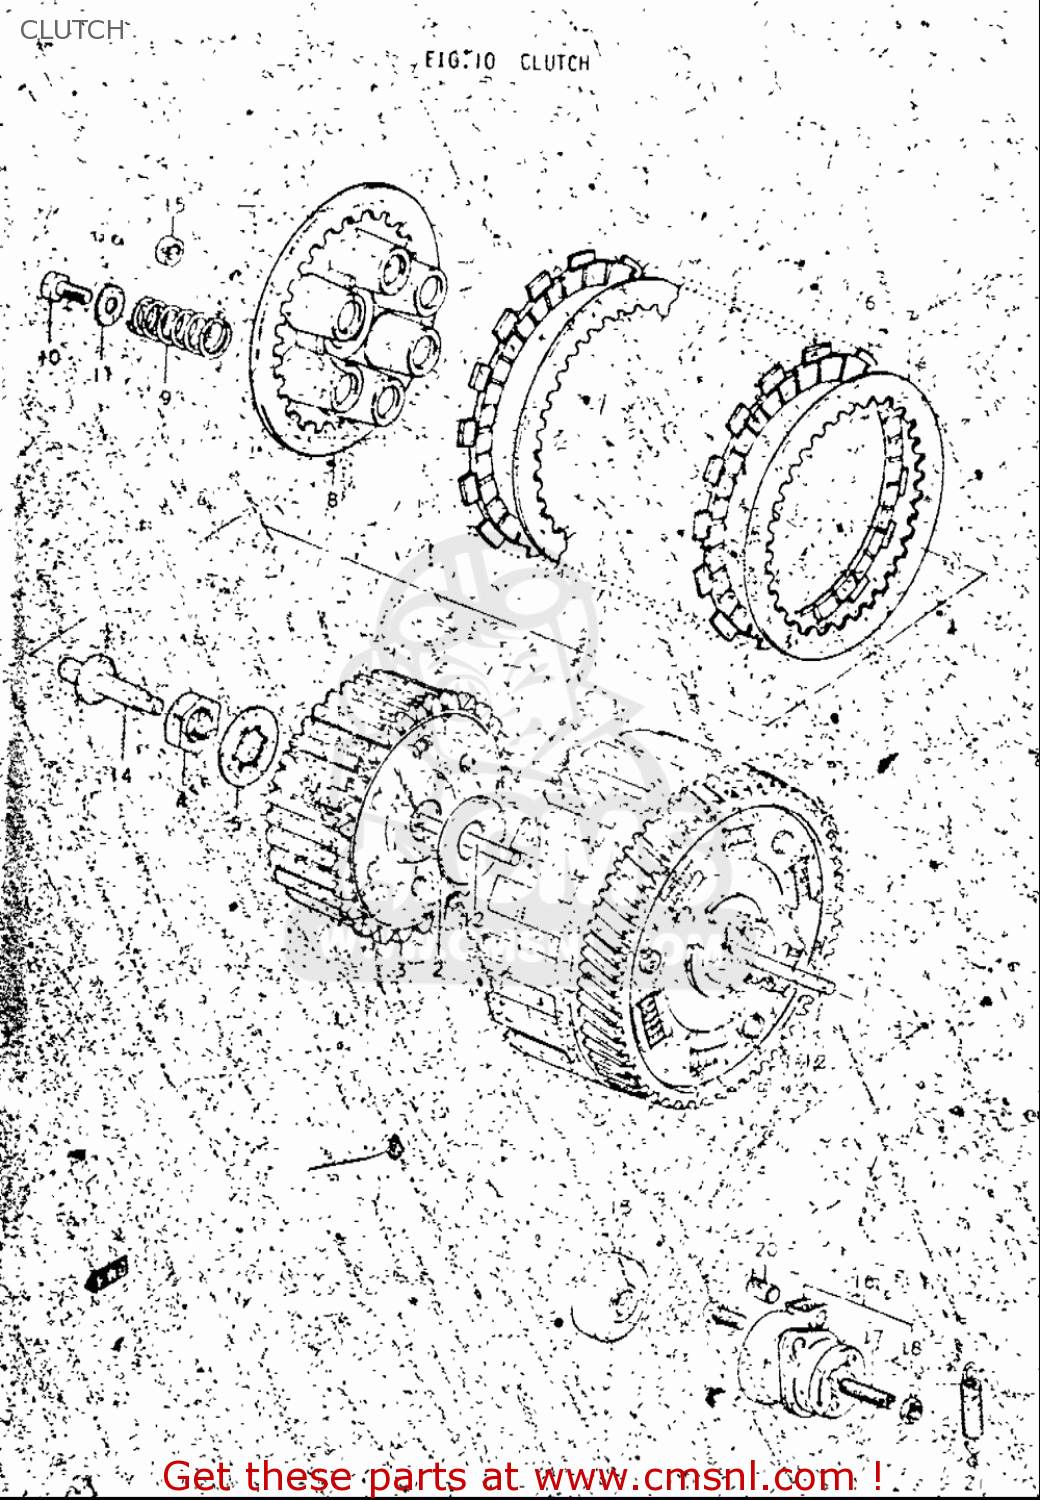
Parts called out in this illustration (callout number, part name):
1	GEAR ASSEMBLY,PRIMARY DRIVE
2	WASHER(20X44X3)
4	NUT
5	WASHER,LOCK
6	PLATE,CLUTCH DRIVE(T:3.5) (NAS)
7	PLATE,CLUTCH DRIVEN(T:2.0) (NAS)
9	SPRING
10	BOLT
11	WASHER(6.5X20X1.6)
12	ROD,CLUTCH PUSH
13	SEAL,OIL (6X30X5)
15	SEAL,OIL (10X17X5)
16	SCREW ASSY,CLUTCH RELEASE
17	SCREW(6X25)
18	NUT
19	SCREW
20	PIECE,RELEASE ARM END
21	SPRING
